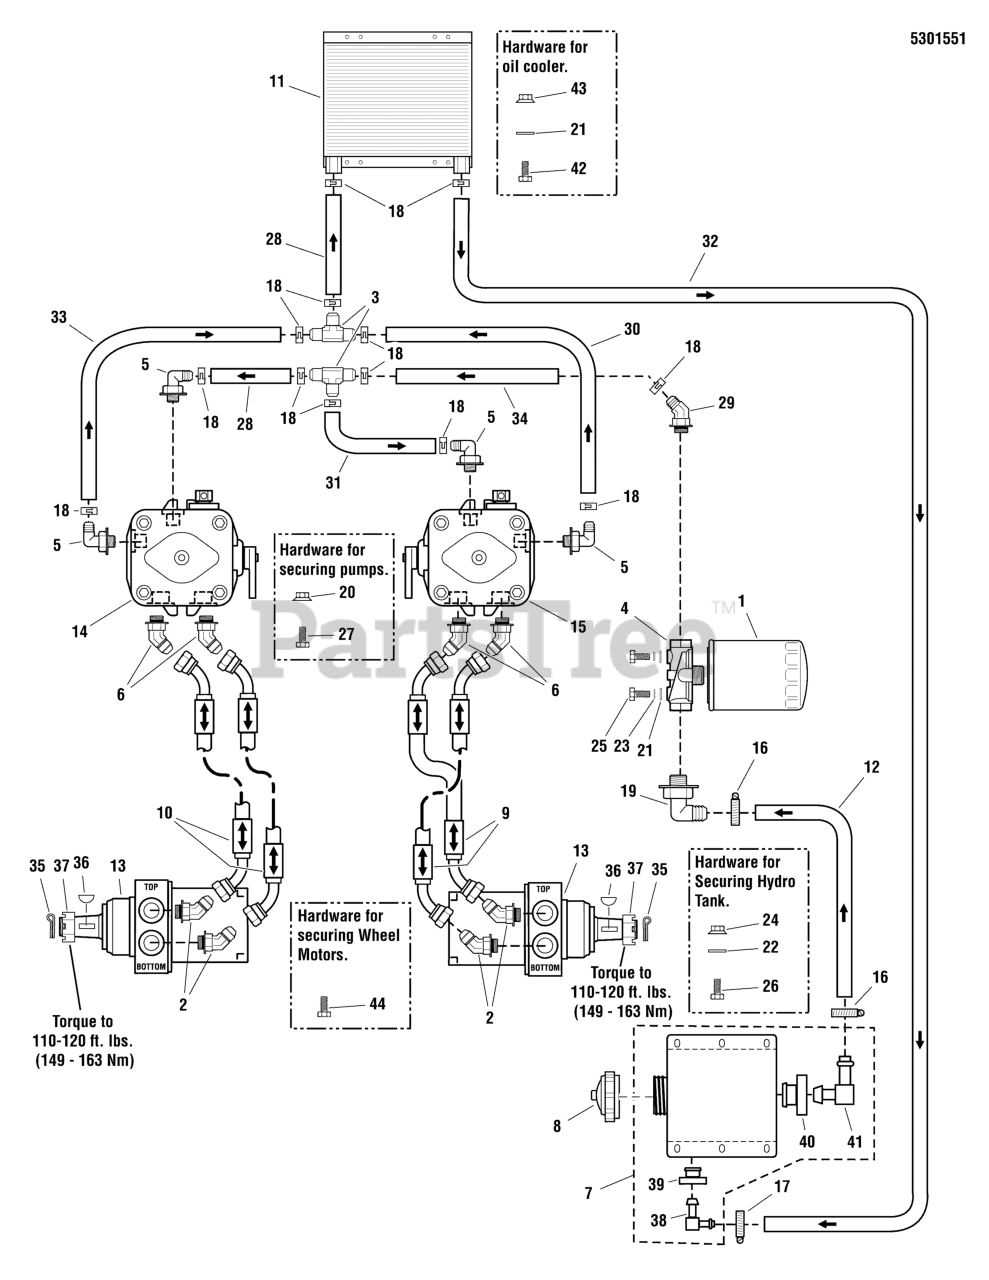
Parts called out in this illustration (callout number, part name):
1	FILTER, OIL
2	FITTING, #8 JIC - #10 O-RING, 45 DEG.
3	FITTING, TEE, 1/2 HOSE
4	FILTER HEAD, HYDRAULIC
5	ADAPTER, 90 DEG, 9/16-3/8 BARB
6	FITTING, #8 JIC - #8 O-RING, 45 DEG.
7	TANK, HYDRAULIC, ASSEMBLY
8	CAP, HYDRAULIC, SHIELDED VENT
9	HOSE ASM,RH, LH PUMP PORT BOT MOTOR PORT
10	HOSE ASM,LH, LH PUMP PORT BOT MOTOR PORT
11	OIL COOLER, .75 X 11.0 X 24 PLATES
12	HOSE, OIL SUPPLY, RES-FILTER
13	WHEEL MOTOR, HGM-15P-7131
14	PUMP, 12CC-LH,HGEAR (PK-2HBQ-LV1X-XXXX)
15	PUMP, 12CC-RH, HGEAR(PK-2KBQ-L81X-XXXX)
16	CLAMP, #10 HOSE, STAINLESS
17	CLAMP, #4 HOSE, STAINLESS
18	CLAMP, HOSE
19	ADAPTER, 90 DEG, 9/16-5/8 BARB
20	NUT, HEX, 7/16-14, SER, FLG, GD5, YZ
21	WASHER, 1/4 SAE
22	WASHER, 5/16" SAE
23	WIRE LOOM, 5/8 ID 36" LONG
24	NUT, 5/16-18 HEX NYLOCK FLANGE
25	BOLT, 1/4-20 X 3/4 GD5 YZ
26	BOLT, 5/16-18 X 1 GD5 YZ
27	BOLT, 7/16-14 X 1-1/4 GD5 YZ
28	HOSE, 3/8" PUSH-LOCK, 10.00"
29	ADAPTER, 45 DEG, 9/16-3/8 BARB
30	HOSE, 3/8" PUSH-LOCK, 12.00"
31	HOSE, 3/8" PUSH-LOCK, 3.50"
32	HOSE, 3/8" PUSH-LOCK, 41.50"
33	HOSE, 3/8" PUSH-LOCK, 6.50"
34	HOSE, 3/8" PUSH-LOCK, 8.00"
35	PIN, COTTER, 1/8 X 2" (SV)
36	WOODRUFF KEY (SV)
37	NUT, CASTLE, 3/4-20
38	FITTING, ELBOW, 3/8" (SV)
39	BUSHING-FUEL TANK RED RUBBER
40	GROMMET (SV)
41	FITTING, ELBOW, 5/8" (SV)
42	HHCS, 1/4-20 X 0.625, GR5, ZINC/CLEAR
43	NUT, 1/4-20 HEX NYLOCK FLANGE
44	BOLT, 3/8-16 X 1 W/ PATCH
